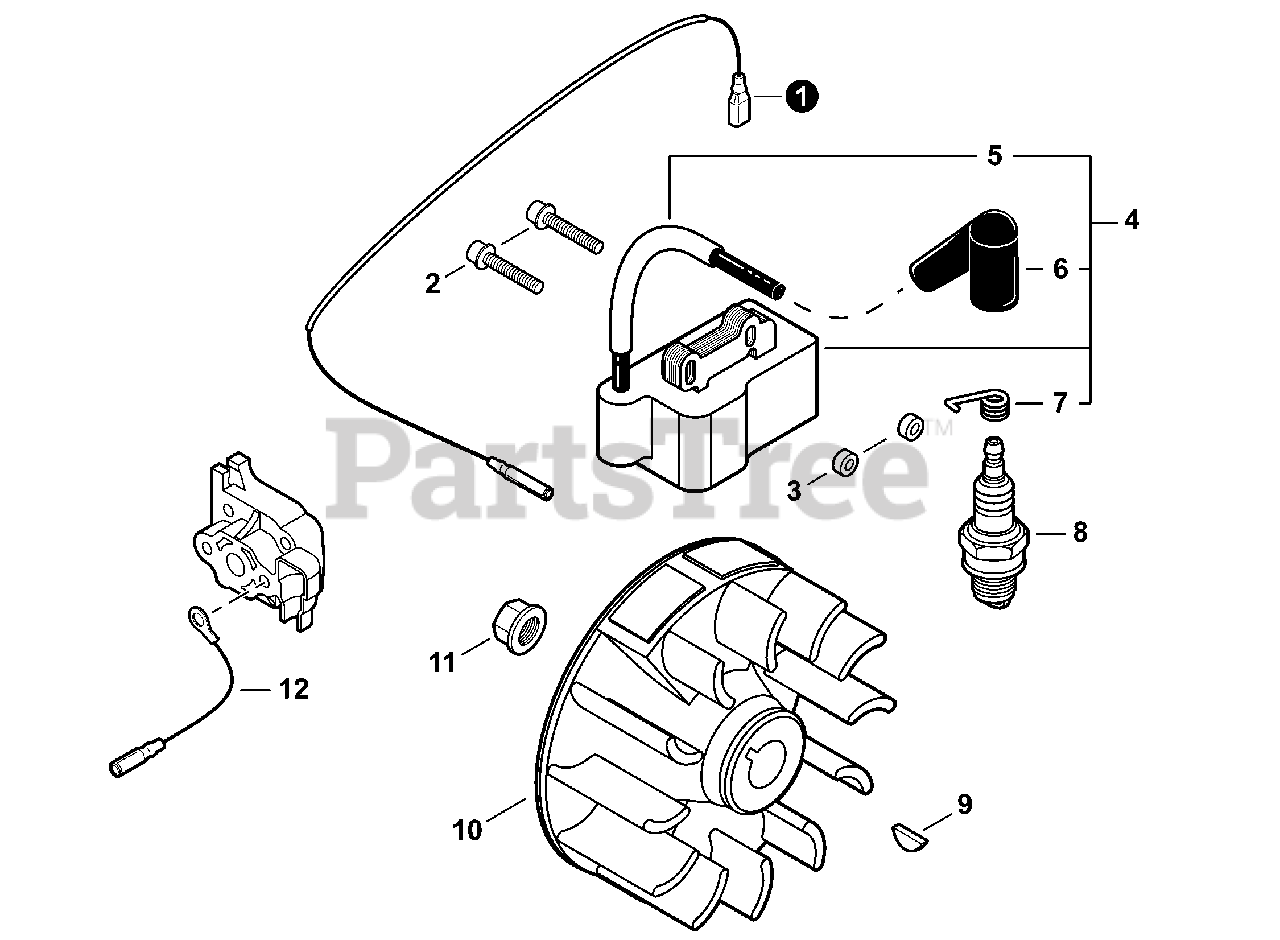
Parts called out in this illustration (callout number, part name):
1	LEAD, IGNITION L= 220mm
2	BOLT M4×26
3	INSULATOR 4.2×11×6
4	COIL ASSY, IGNITION
5	SLEEVE, INSULATOR
6	CAP, SPARK PLUG
7	TERMINAL, SPARK PLUG
8	SPARK PLUG - CMR5H
9	KEY, WOODRUFF 3×10
10	FLYWHEEL
11	NUT, CRANKSHAFT M8
12	LEAD, GROUND L= 110mm
